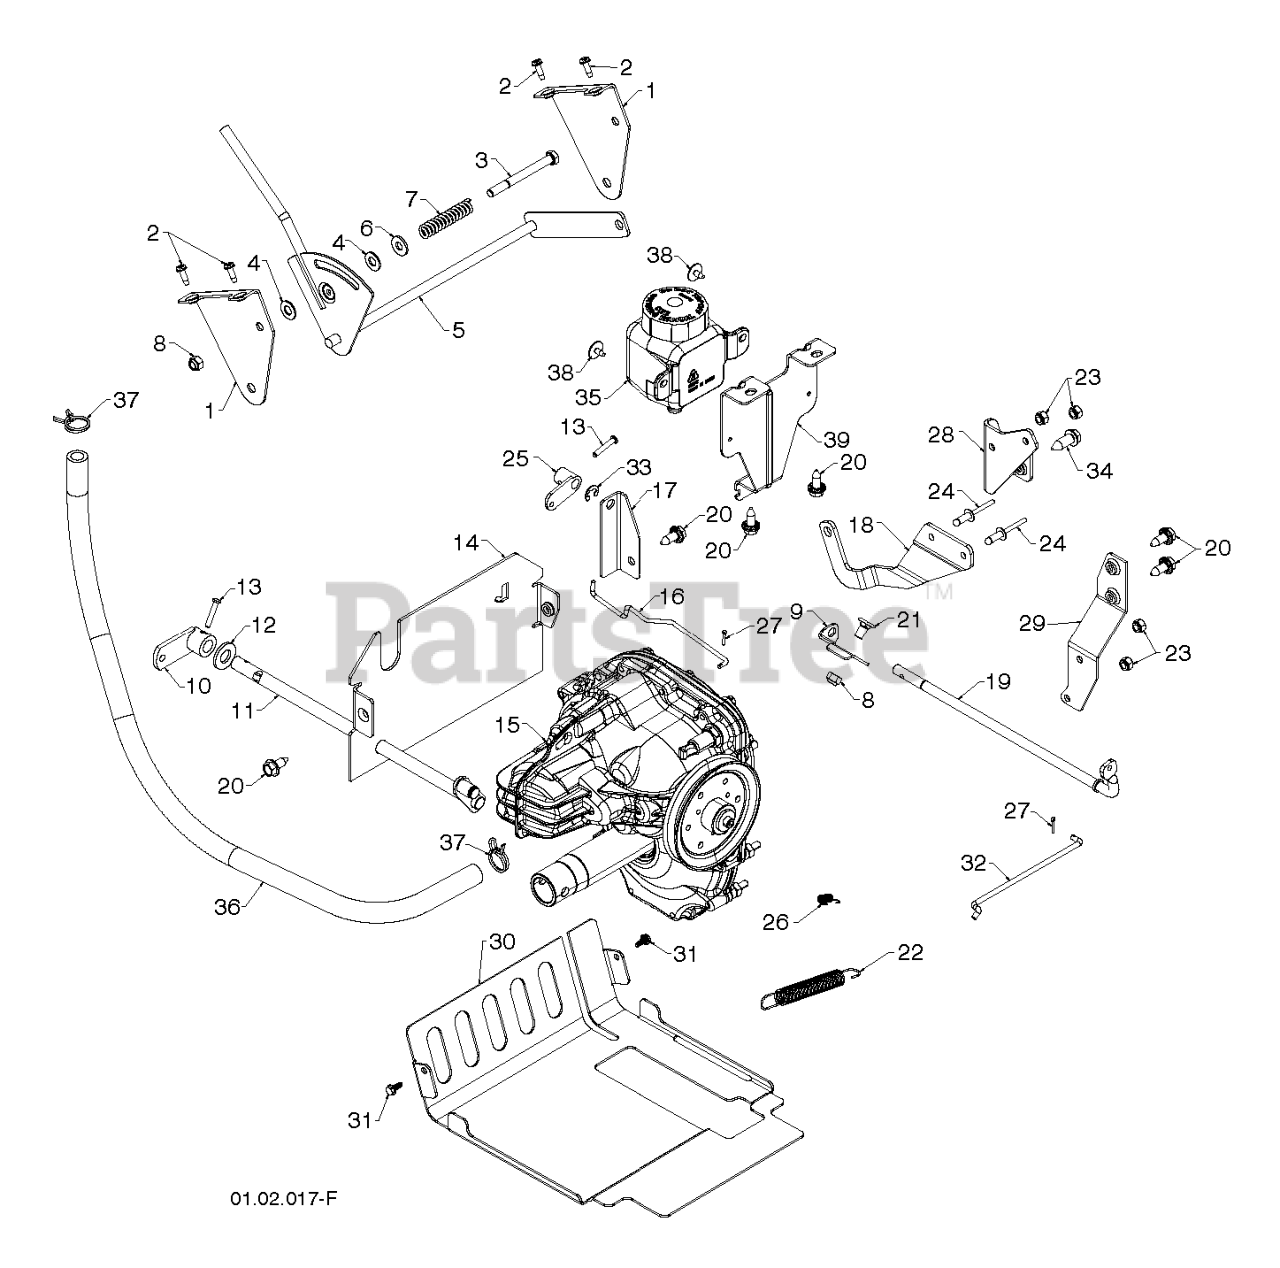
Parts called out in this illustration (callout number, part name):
1	BRACKET.SHIFT.HYDRO
2	SCREW #10-24 X 5/8
3	SCREW 5/16-18 X 3.25
4	WASHER, NYLON FRICTION
5	LEVER ASSEMBLY, SPEED CONTROL
6	WASHER.20X8.5
7	SRPING.FRICTION.HYDRO
8	NUT.71038.31-18.HEX.NYLOCK
9	BRACKET.HYD.CLUTCH.
10	ARM.CONTRL.PIN.TRACK
11	CONTROL.SHAFT.ASM
12	WASHER.FLAT.1/2
13	CLEVIS PIN
14	PLATE.REAR.HYDRO.TRACK.ORANGE
15	TRANSMISSION 321-0410
16	ROD, BYPASS VALVE
17	BRACKET.HYD.CLUTCH.REAR
18	ARM.CONTROL.HYDRO.SNOW
19	SHAFT.HYD.CLUTCH
20	BOLT.HEX.HD.WASHER.5/16-18X.75
21	BOLT.CARRIAGE.5/16-18X
22	SPRING, BRAKE
23	LOCKNUT.NYLOC.1/4-20
24	RIVET.POP.1/4X.475
25	ARM.HYD.CLUTCH
26	SPRING, TRACTION IDLER
27	RETAINER CLIP
28	BRACKET, ANTI-ROTATE
29	STRAP.TORQUE.HYDRO
30	COVER.TRANSMISSION.TRACK.BLACK
31	SCREW1032X.500
32	ROD.HYDRO CLUTCH
33	E-RING.RETAINER.REINFORCED.375
34	SCREW 5/16-18X1
35	TANK.EXPANSION.350ML 71328
36	HOSE.EXPANSION.TANK.TRACK
37	CLAMP.SPRING.HOSE.795
38	SCREW, HEX HEAD, TAPPING
39	BRACKET.EXPANS.TANK.TRACK.GREY
